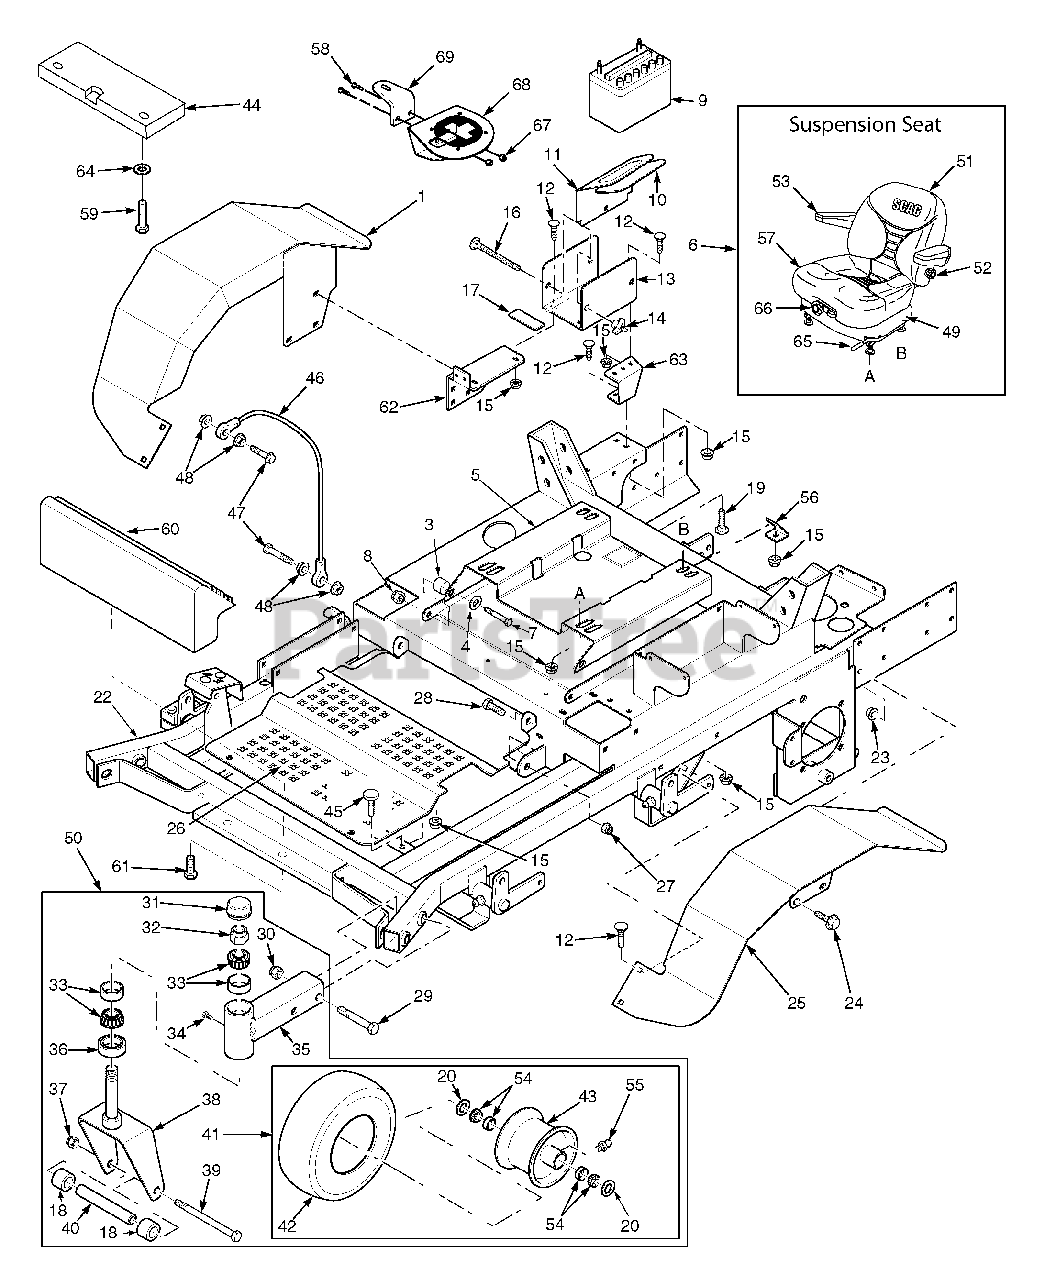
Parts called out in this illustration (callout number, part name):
1	Fender Weldment, RH
2	Bolt, Hex Head, 5/16-18 x 1, Zinc
3	Spacer
4	Flatwasher, 3/8-.391 x .938 x .105
5	Seat Plate
6	Suspension Seat Assembly
7	Bolt, Hex Head 3/8-16 x 2.0"
8	Nut, Elastic Stop 3/8-16
9	Battery (Not Avail. through Scag)
10	Pad, Battery Cover
11	Cover, Battery
12	Bolt, Carriage 5/16-18 x 3/4"
13	Plate, Battery Box
14	Wing Nut, 1/4-20 x 3/4"
15	Nut, Hex Serrated Flange 5/16-18
16	Bolt, Carriage 1/4-20 x 6"
17	Rubber Pad
18	Spacer, Caster Wheel
19	Bolt, Carriage 5/16-18 x 1"
21	Lock Nut, 3/8-16, Elast. Stop
22	Main Frame
23	Nut, Hex Serrated Flange 3/8-16
24	Screw, Hex Serrated Flange 3/8-16 x 1"
25	Fender Weldment, LH
26	Foot Plate
27	Nut, Hex Elastic Stop 3/8-16
28	Bolt, Hex Head 3/8-16 x 1"
29	Bolt, Hex Head 5/8-11 x 4"
30	Nut, Hex Elastic Stop 5/8-11
31	Cap, Grease
32	Nut, Hex Elastic Stop 1.0-14
33	Bearing W/Race
34	Plug, 1/4-28 THD Form
35	Extention Weldment, Caster 61A (LH)
36	Seal, 2.00 OD. x 1.625 Bore
37	Nut, Hex Elastic Stop 1/2-13
38	Yoke Weldment, Caster (61A & 72A)
39	Bolt, Hex Head 1/2-13 x 9-1/2" (61A & 72A)
40	Sleeve, Caster Wheel (61A, 72A)
41	Wheel Assy
42	Tire, 13 x 6.50 4-Ply (61A, 72A)
43	Rim Assembly, 61A & 72A
44	Weight (61" cutter deck only)
45	Bumper, Rubber
46	Cable, Seat Stop
47	Bolt, Hex Head 1/4-20 x 1-1/4"
48	Nut, Hex Serrated Flange 1/4-20
49	Shock Absorber Kit
50	Caster Wheel Assy 61A (LH)
51	Back Cushion Kit
52	Lumbar Kit
53	Armrest Only
54	Bearing w/ Race
55	Grease Fitting
56	Seat Stop
57	Seat Cushion Kit Seat Drain Kit
58	Bolt, Hex Head 1/4-20 x 3/4"
59	Bolt, Hex Head 1/2-13 x 3.5"
60	Footrest
61	Bolt, Hex Head 1/2-13 x 1.5"
62	Mounting Bracket, Battery
63	Support Bracket, Battery Box
64	Flat Washer 1/2-.562 x .1.375 x .109
65	Seat Adjustment, Track Set
66	Weight Adjustment Kit
67	Nut, Elastic Stop 1/4-20
68	Cup Holder Assembly
69	Mounting Bracket, STT Cup Holder
70	Bolt, Hex Head 1/4-20 x 3/4"
